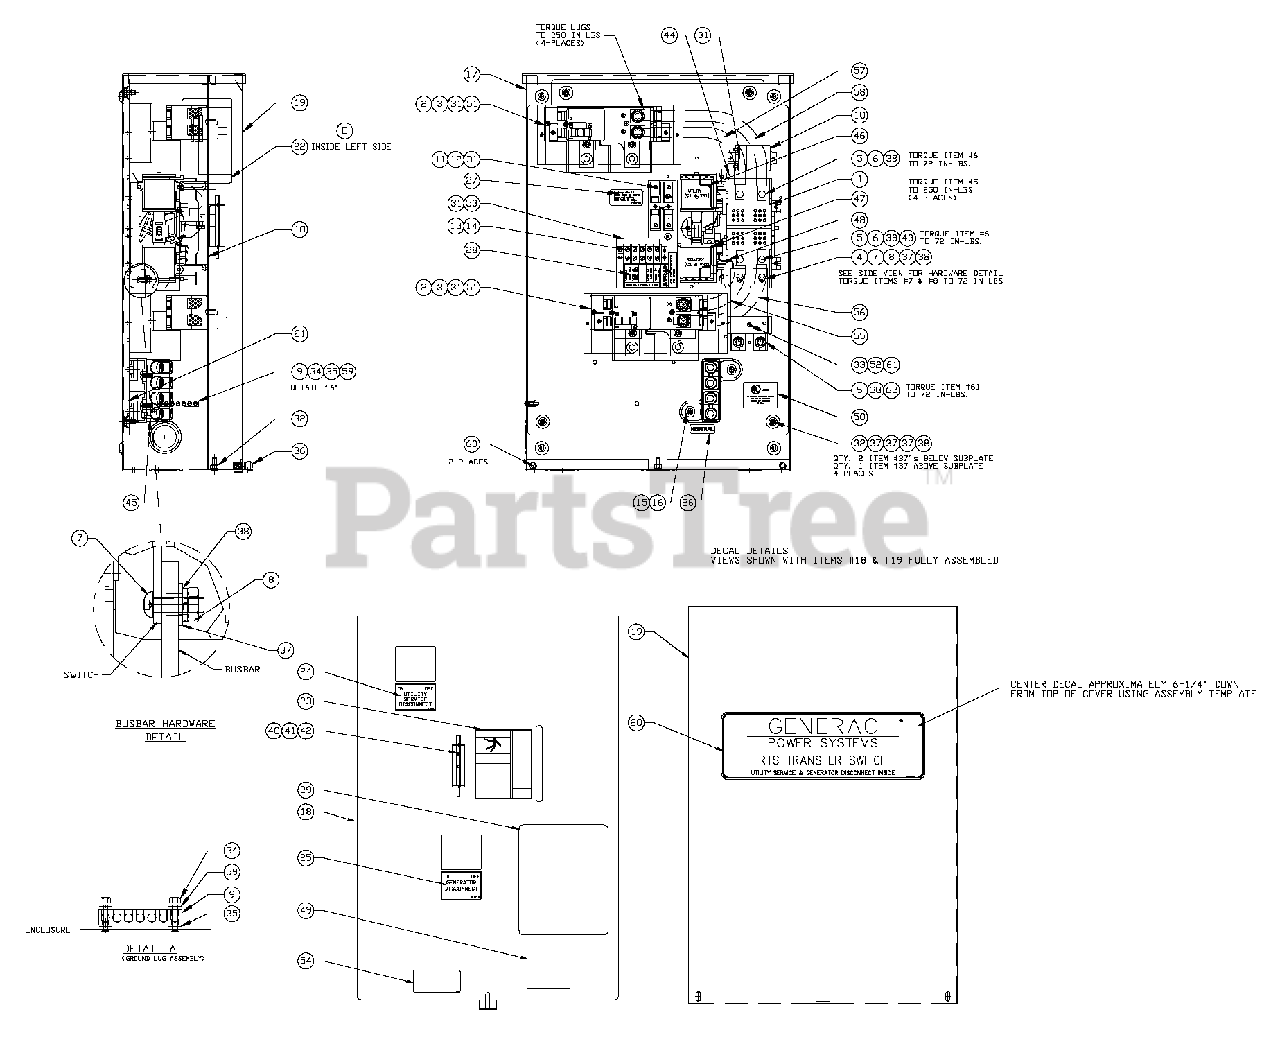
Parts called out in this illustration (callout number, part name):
1	TRANSFER SW. HSB 200A 2P 250V
2	CIRCUIT BREAKER, 200A 2-POLE
3	BASE CIRCUIT BREAKER 2-POLE
4	BUSBAR 200A HSB XFER SW
5	LUG SOLDERLESS 250-#6 AL/CU
6	SCREW BHSC 1/4-20 X 3/8"
7	SCREW BHSC 1/4-20 X 3/4
8	NUT 1/4-20
9	GROUND BAR (5) 4-14 AWG CONN
10	RELAY PNL 12VDC DPDT
11	FUSEBLOCK 30A 600V 2 POLE
12	FUSE 5A X BUSS HLDR73591
13	BLOCK TERM 20A 5 X 6 X 1100V
14	RIVET POP .156 X .67
15	ASSY NEUTRAL BLOCK 200A
16	SCREW HHTT M6-1.0 X 12 MM
17	WELDMENT TRANSFER SWITCH ENCL
18	COVER INSIDE 200A DUAL BREAKER
19	COVER TRANSFER SWITCH
20	DECAL TRANSFER SWITCH RTS SE
21	SUBPLT XFER SW HSB SERV ENT
22	DECAL DATA
23	DECAL MANUAL OPERATING HANDLE
24	DECAL UTILITY DISCONNECT
25	DECAL GENERATOR DISCONNECT
26	DECAL NEUTRAL
27	DECAL FUSE REPLACEMENT
28	DECAL TERMINAL STRIP
29	DECAL TEST SEQUENCE
31	SCREW HHTT M4-.7 X 8 BP
32	NUT HEX M6 X 1.0 G8 YEL CHR
33	SCREW HHTT M6-1.0 X 35 YC
34	NUT HEX LOCK M4-0.7 SS NYL INS
35	WASHER SHAKEPROOF EXT #8 STEEL
36	THUMB SCREW 1/4-20x1/2
37	WASHER FLAT 1/4-M6 ZINC
38	WASHER LOCK M6-1/4
40	BRACKET ARM EXTENDER
41	SCREW HWHS #6-25 X 3/8
42	ARM EXTENDER PIN
43	90 DEGREE DN SPADE CONNECTOR
44	SCREW HHTT M5-0.8 X 10 BP
48	WIRE-E1
49	DECAL TERMINAL SHOCK HZD BI
50	DECAL-UL LIST HSB
51	RISER CIRCUIT BREAKER
52	BLOCK PHENOLIC
53	FUSE BRACKET
54	DECAL LIVE CIRCUIT ENG/FRN/SPN
55	WIRE RED 3/0 E1
56	WIRE RED 3/0 E2
57	WIRE BLACK 3/0 N1
58	WIRE BLACK 3/0 N2
59	WASHER FLAT M4
60	NUT TRIC 1/4-20 X .525
61	BLOCK, PHENOLIC/BUSBAR COVER
62	SCREW BHSC 1/4-20 X 1/2
